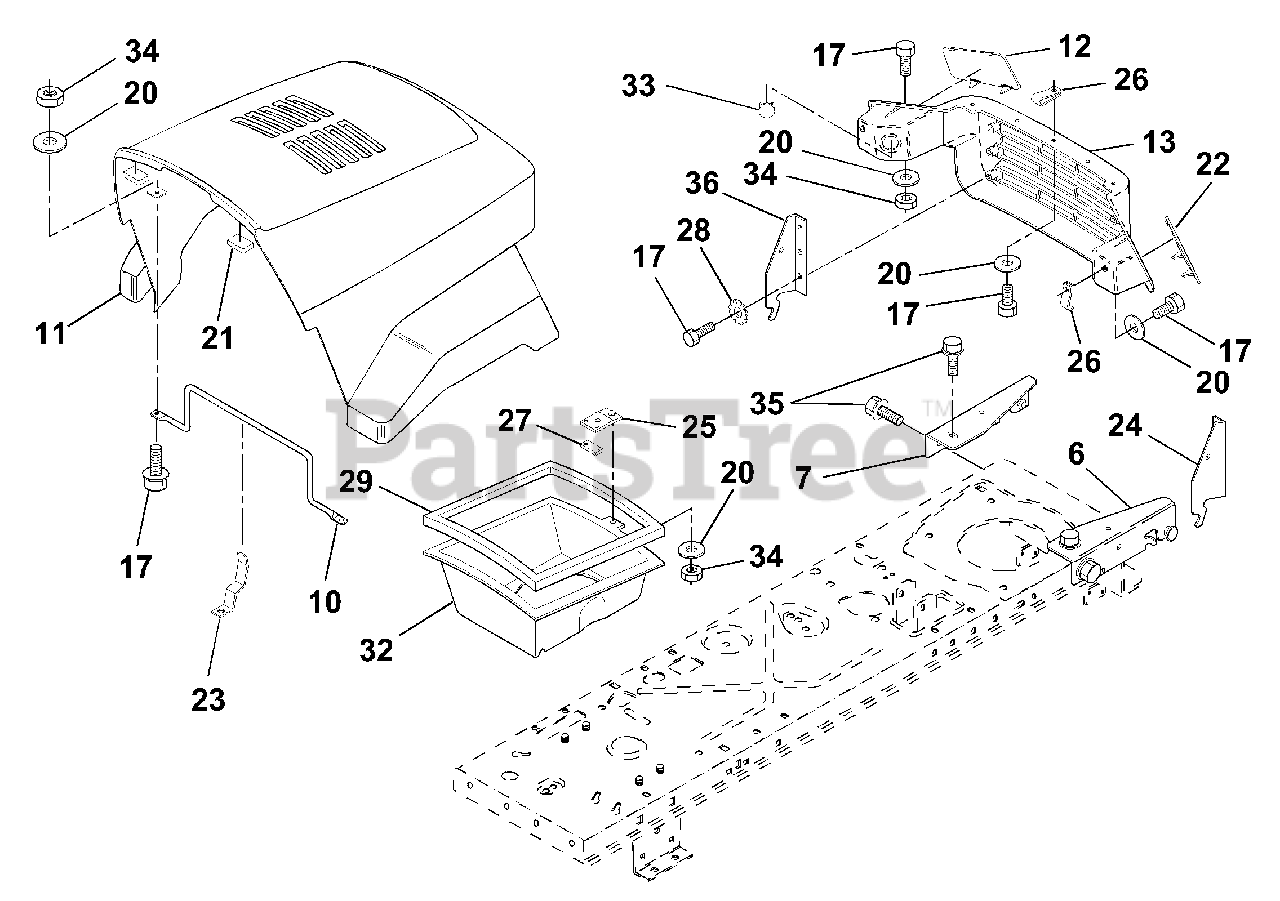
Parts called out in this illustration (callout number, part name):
6	Bracket Asm. Pivot Hood RH
7	Bracket Asm. Pivot Hood LH
10	Brace Hood
13	Grille
17	Bolt Fin Hex 1/4-20 x 5/8
20	Washer, Flat 1/4
21	Bumper Hood
23	Latch Hood
24	Bracket Pivot Hood RH
25	Clip Asm. Duct Air
26	Clip Tinnerman
27	Clip Tinnerman
28	Washer Lock Ext. Tooth
29	Strip Foam
32	Duct Air Hood
33	Plug, Socket, Light
34	Nut Crownlock 1/4-20 Unc
35	Screw Thdrol 5/16-28 x 3/4
36	Bracket Pivot Hood LH
